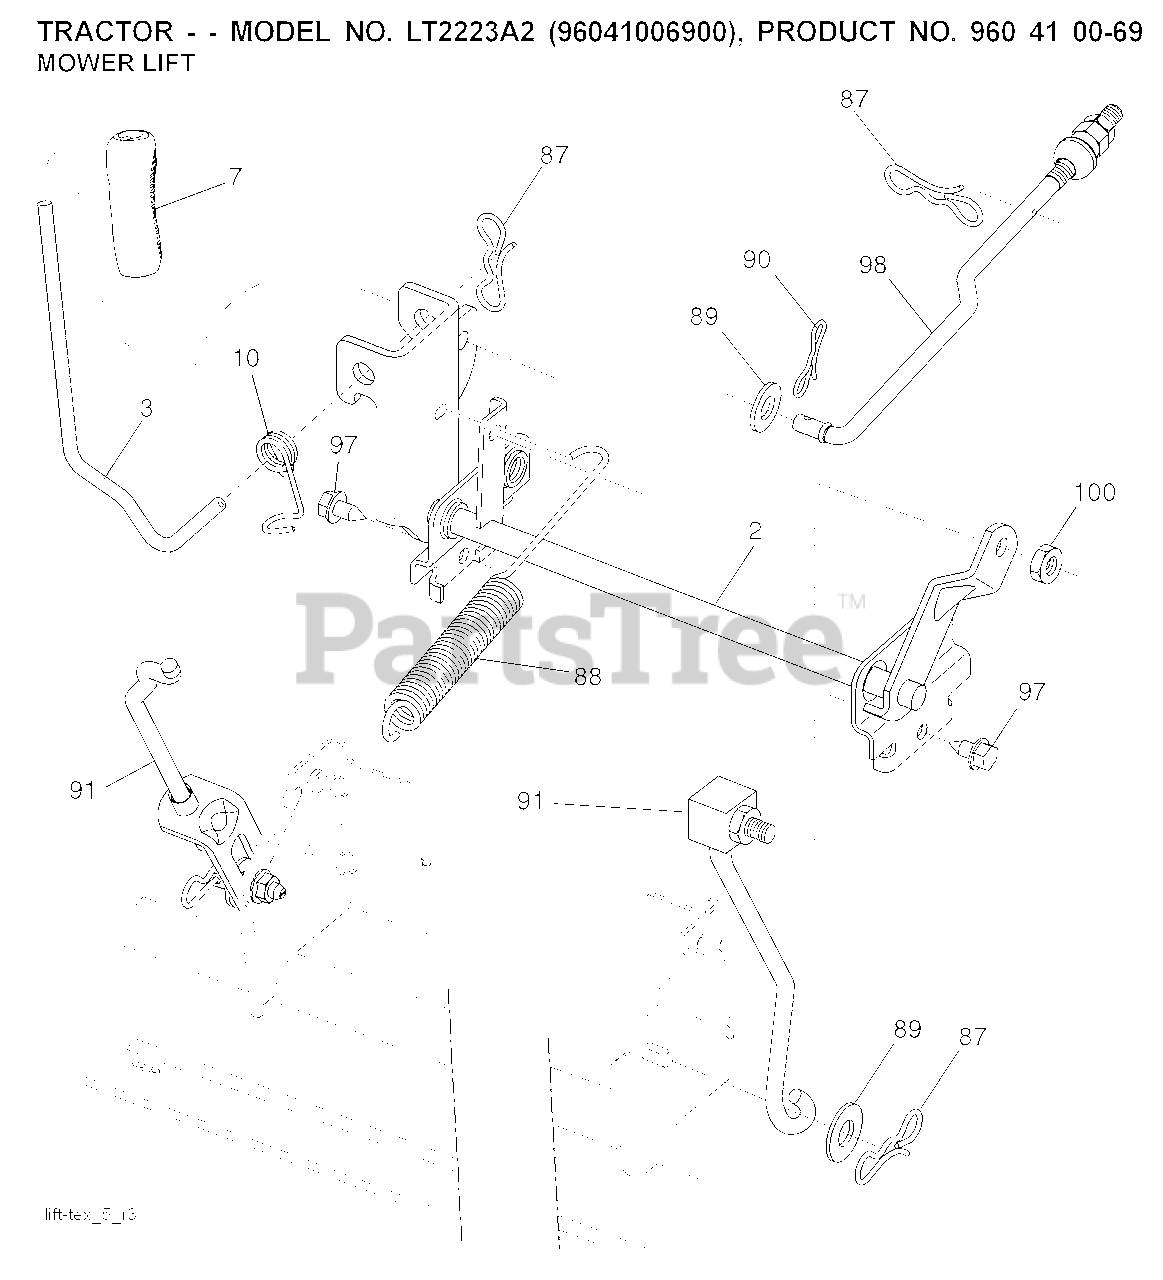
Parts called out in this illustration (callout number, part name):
2	SHAFT.ASM.LIFT.CROSS.H
3	LEVER.LIFT.HANDLE.LT
7	GRIP.HANDLE.LIFT.PVC.BLACK
10	SPRING.TORSION.LIFT.HANDLE
87	PIN.COTTER.7/16.BOW TI
88	SPRING.LIFT.ASSIST
89	WASHER.CLEAR.ZINC
90	PIN.COTTER.5/16.BOW TI
91	LINK.ASM.LIFT.REAR
97	SCREW, 3/8-16X3/4
98	LINK.ASM.SUSP.FRONT.MW
100	LOCKNUT
